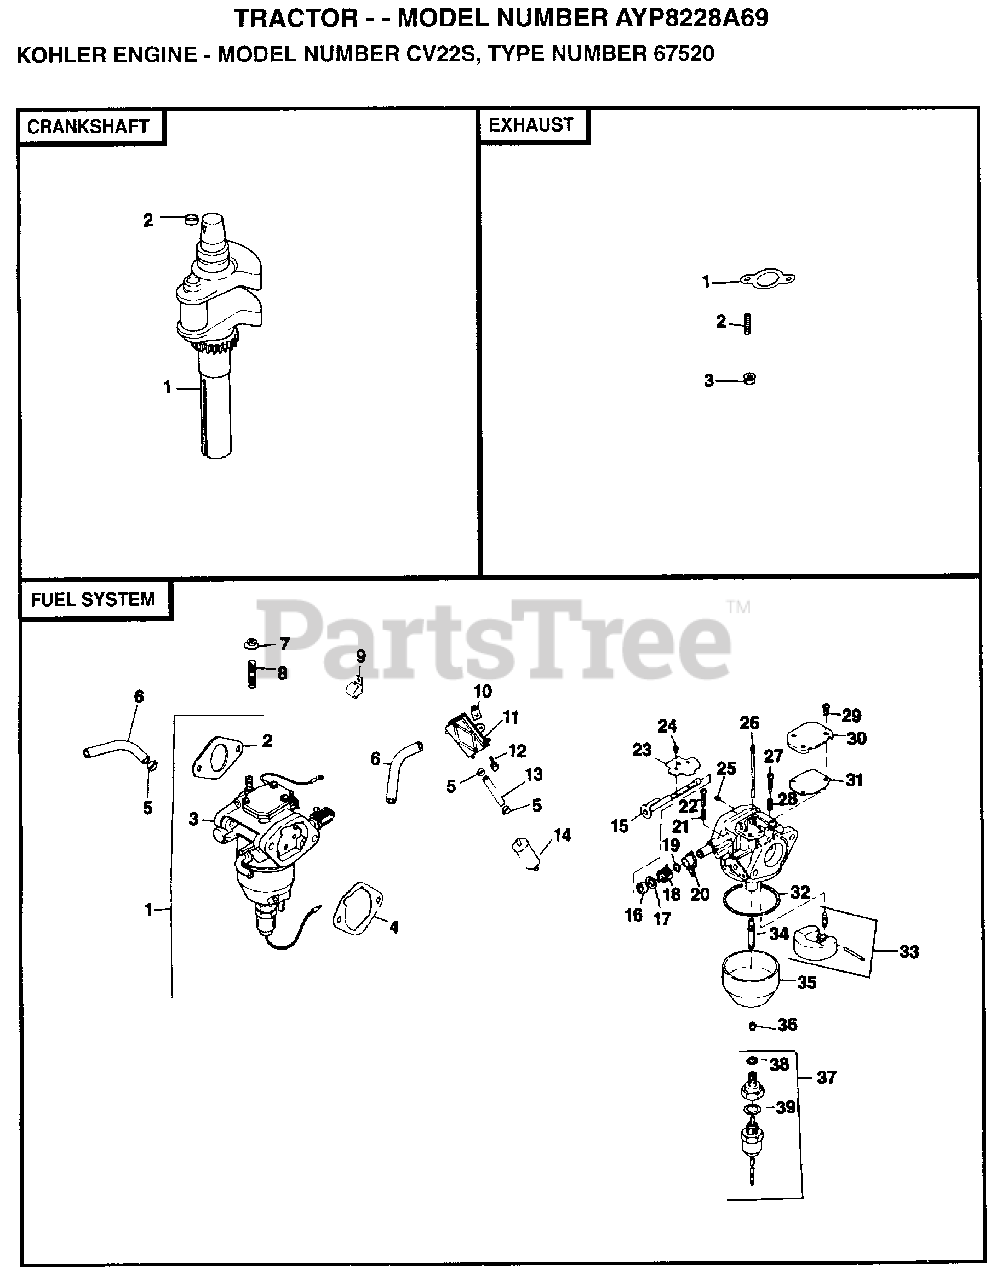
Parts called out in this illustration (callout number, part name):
1	KIT, CARBURETOR WITH GASKET
1	GASKET
2	STUD. EXHAUST MANIFOLD
3	CARBURETOR ASSEMBLY
25	JET, AIR BLEED
33	KIT, FLOAT REPAIR
37	KET, SOLENOID VALVE
